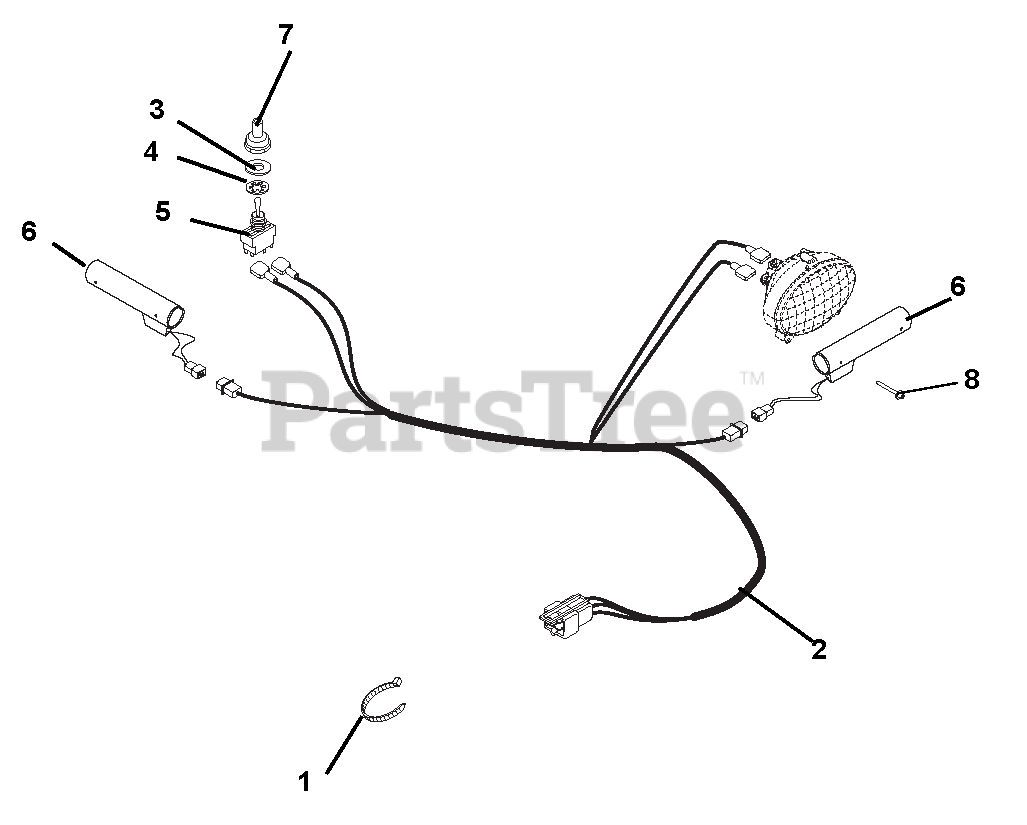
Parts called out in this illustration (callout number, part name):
1	CABLE TIE LG 5-1/2
2	HARNESS, WIRE-LIGHT HANDWARMER
3	WSHR-FL-STL .505X.875X.024 PL
4	WSHR-LK-INT .563X.040 YWZC
5	SWITCH, ON/OFF
6	HEATED GRIP, MAGURA
7	BOOT, SWITCH
8	RVT-POP .125 X .313 AL BLACK
